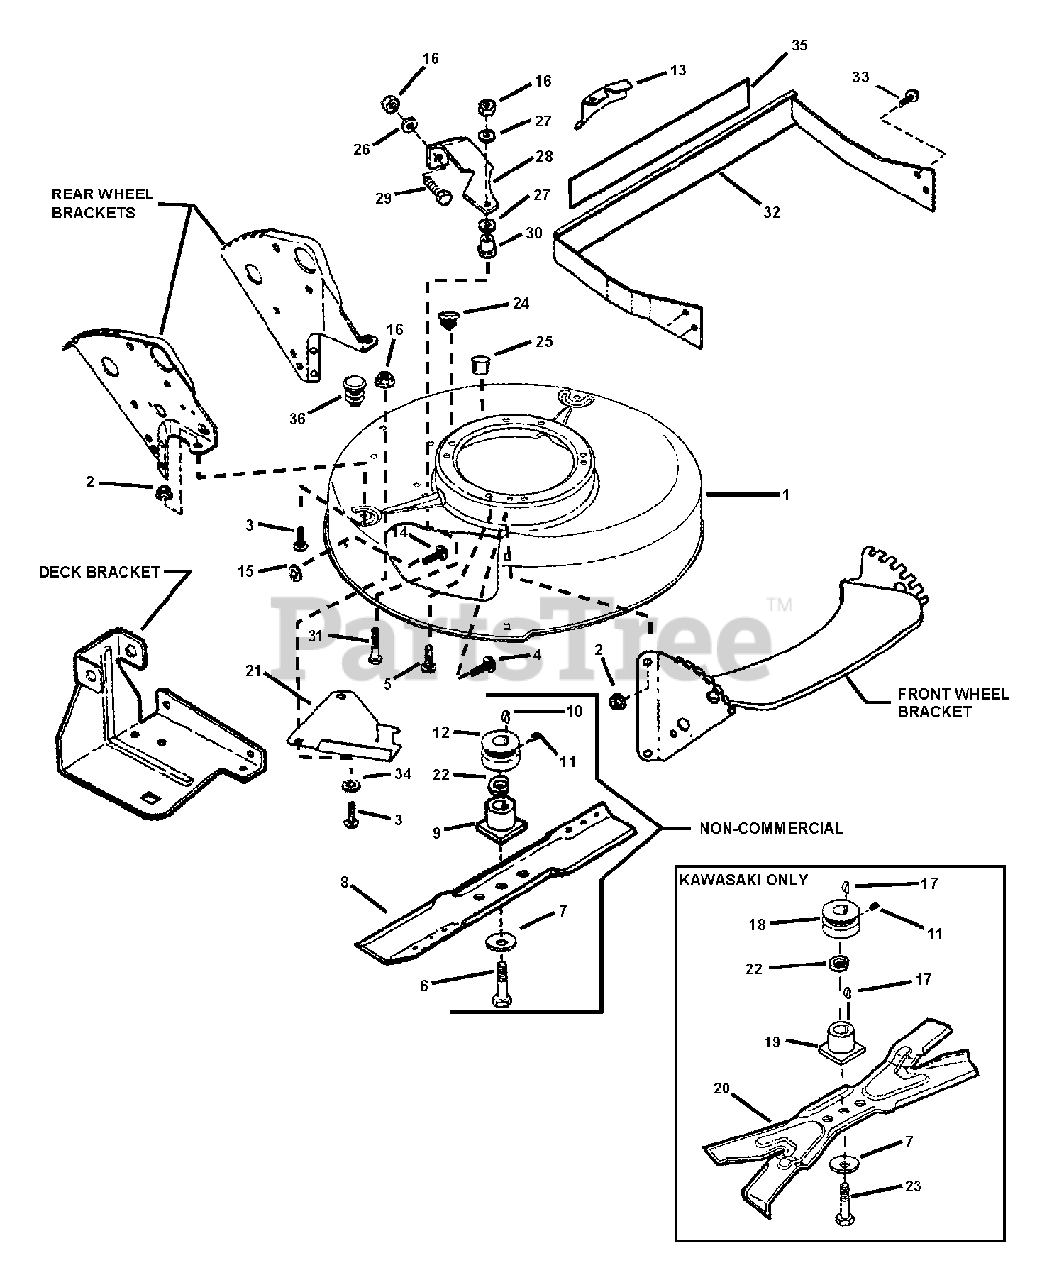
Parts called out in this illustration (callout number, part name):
1	DECK, Mower
2	NUT, 5/16-18 Hex Flange Lock, Grade 5
3	BOLT, 5/16-18 x 1/2" Short Neck Carriage (Gr. 5)
4	BOLT, 5/16-18 x 1-1/8" Short Neck Carriage, Grade 5
5	SCREW, 3/8-16 x 1" Self-Tapping (Engine Mounting)
6	SCREW, 3/8-24 x 1-3/4" Hex Head Cap, Grade 5
7	WASHER, Cone
8	BLADE, Cutter
9	HUB, Blade Drive 25mm
10	KEY, Woodruff (Briggs)
11	SCREW, 5/16-18 x 5/16" Hex Socket Set
12	PULLEY, Engine (25mm I.D. x 2-1/8" O.D.)
13	SHIELD, Belt Opening Cover
14	BOLT, 5/16-18 x 3/4" Short Neck Carriage, Grade 5
15	RETAINER, 5/16 Bolt
16	NUT, 5/16-18 Hex Flange Lock, Grade 5
17	KEY, Woodruff
18	PULLEY, Engine (7/8" I.D. x 2-1/8" O.D.)
19	HUB, Blade Drive 7/8"
20	BLADE, Cutter (Mulching)
21	BAFFLE, Belt
22	SPACER
23	SCREW, 3/8-24 x 2" Hex Head Cap, Grade 5
24	PLUG, 5/16" Square Hole
25	PLUG, 5/16" Round Hole
26	WASHER, 5/16" Flat
27	WASHER, 7/16" Flat
28	COVER, Belt
29	SCREW, 5/16-18 x 1/2" Hex Head Cap Grade 5
30	BUSHING
31	BOLT, 5/16-18 x 2-1/4" Hex Flange Lock
32	STRUCTURE, Fender
33	SCREW, 1/4-20 x 1/2" Hex Self-tapping
34	WASHER, 1/2" Flat
35	DECAL, Operator Safety
36	PLUG, Hole
